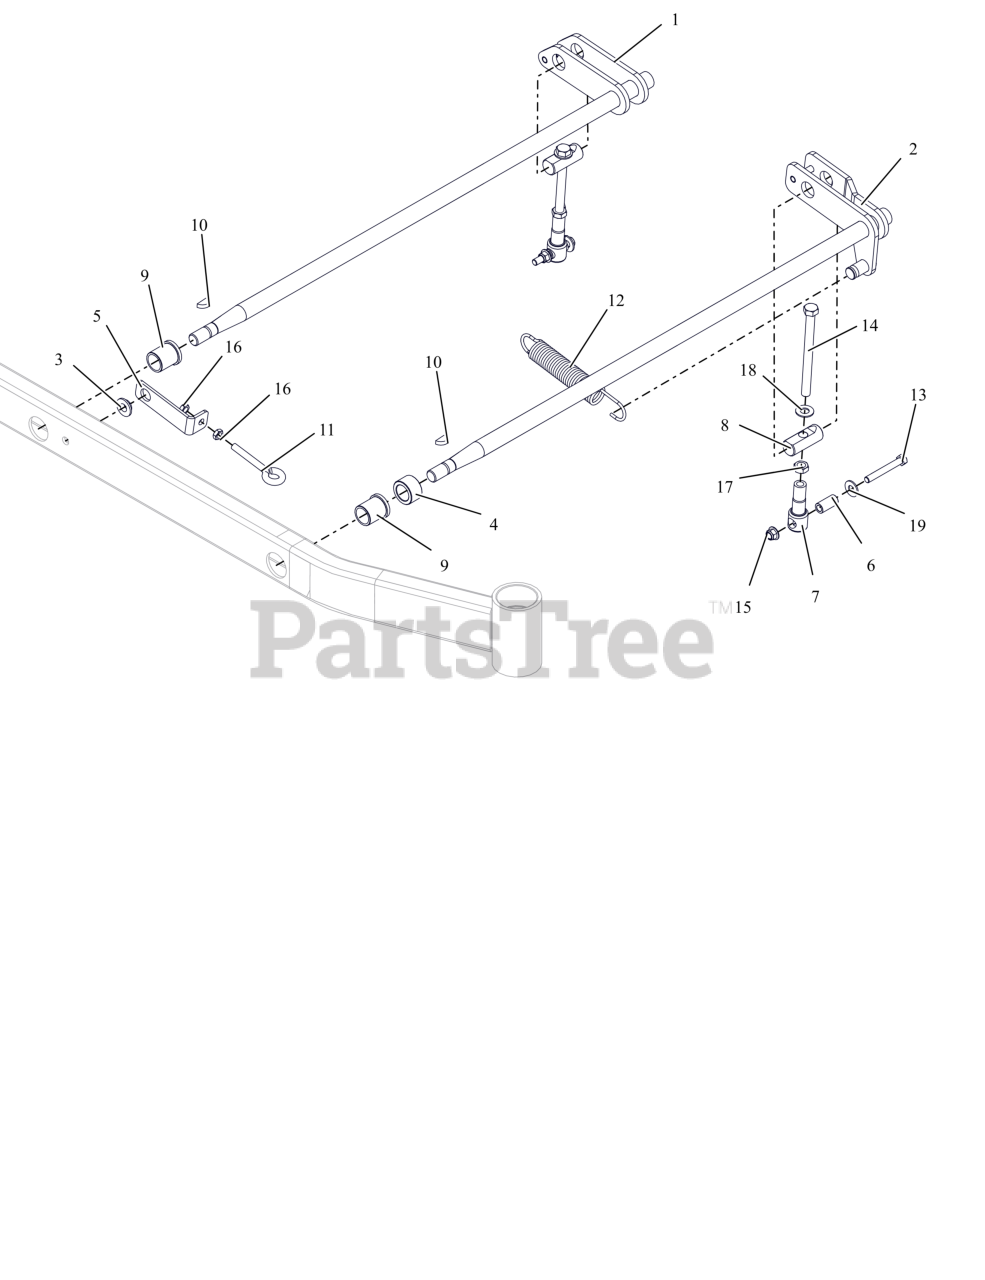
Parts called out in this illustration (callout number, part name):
1	REAR LH DECK LIFT ARM WMT- LF
2	FRT LH DECK LIFT ARM WMT- LF
3	BSHG-FLG .515X.750X.310X1.120
4	SPACER, 1.500 X 1.000 X .880
5	SPRING ANCHOR BRACKET - RED
6	SPACER, DECK LEVELING
7	LINK, DECK LIFT FORMED
8	PIN, DECK LIFT
9	BSHG-FLG 1.00X1.25X1.50X1.50
10	KEY-WDRF .25X1.00 HRD #15
11	BLT-EYE .375-16X2.50 YWZC
12	SG-TENS .162X1.25X8.25 WLD 25
13	BLT, HEX .38-16X2.75 G8 ZCC
14	BLT, HEX .50-13X6.00S G5 ZCC
15	NUT,NYL-FLG .38-16 GF ZCC
16	NUT-JAM .375-16 G2 ZCC
17	NUT-JAM .500-13 G2 ZCC
18	WSHR, FLT .557X1.040X.102 ZCC
19	WSHR,FLT .438X1.00X.083 ZCC
